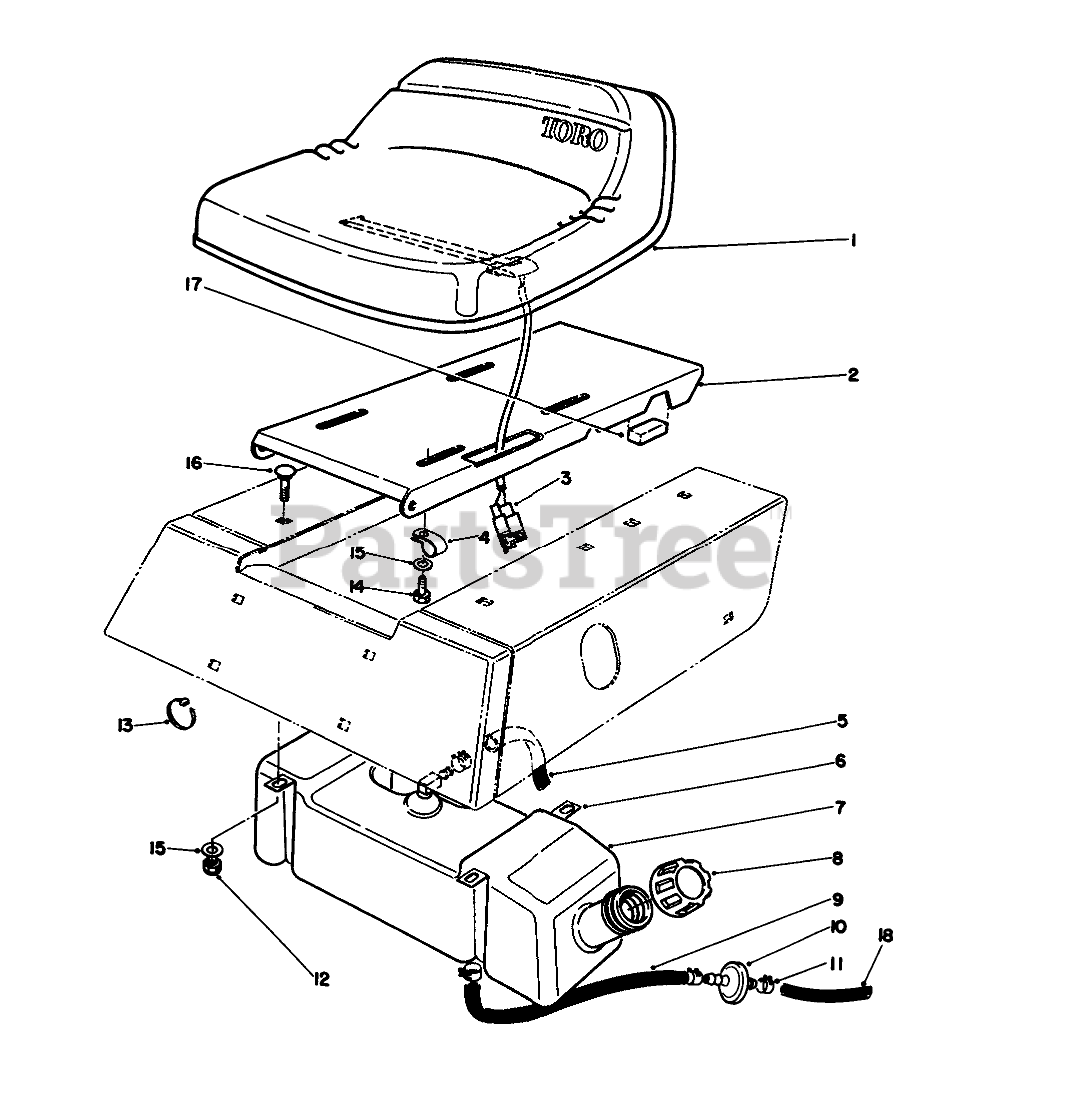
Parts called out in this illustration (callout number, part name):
1	Seat
2	BASE - SEAT
3	SWITCH-SEAT
4	CLIP-FUEL LINE
5	HOSE-FUEL
6	STRAP-GAS TANK
7	TANK-GAS
8	GAS CAP ASM
9	HOSE-FUEL
10	FILTER-FUEL
11	CLAMP-HOSE
12	NUT-LOCK, NI
13	TIE-CABLE
14	SCREW-HH
15	WASHER-PLAIN
16	SCREW-CARR
17	PAD-ISOLATOR
18	HOSE-FUEL
